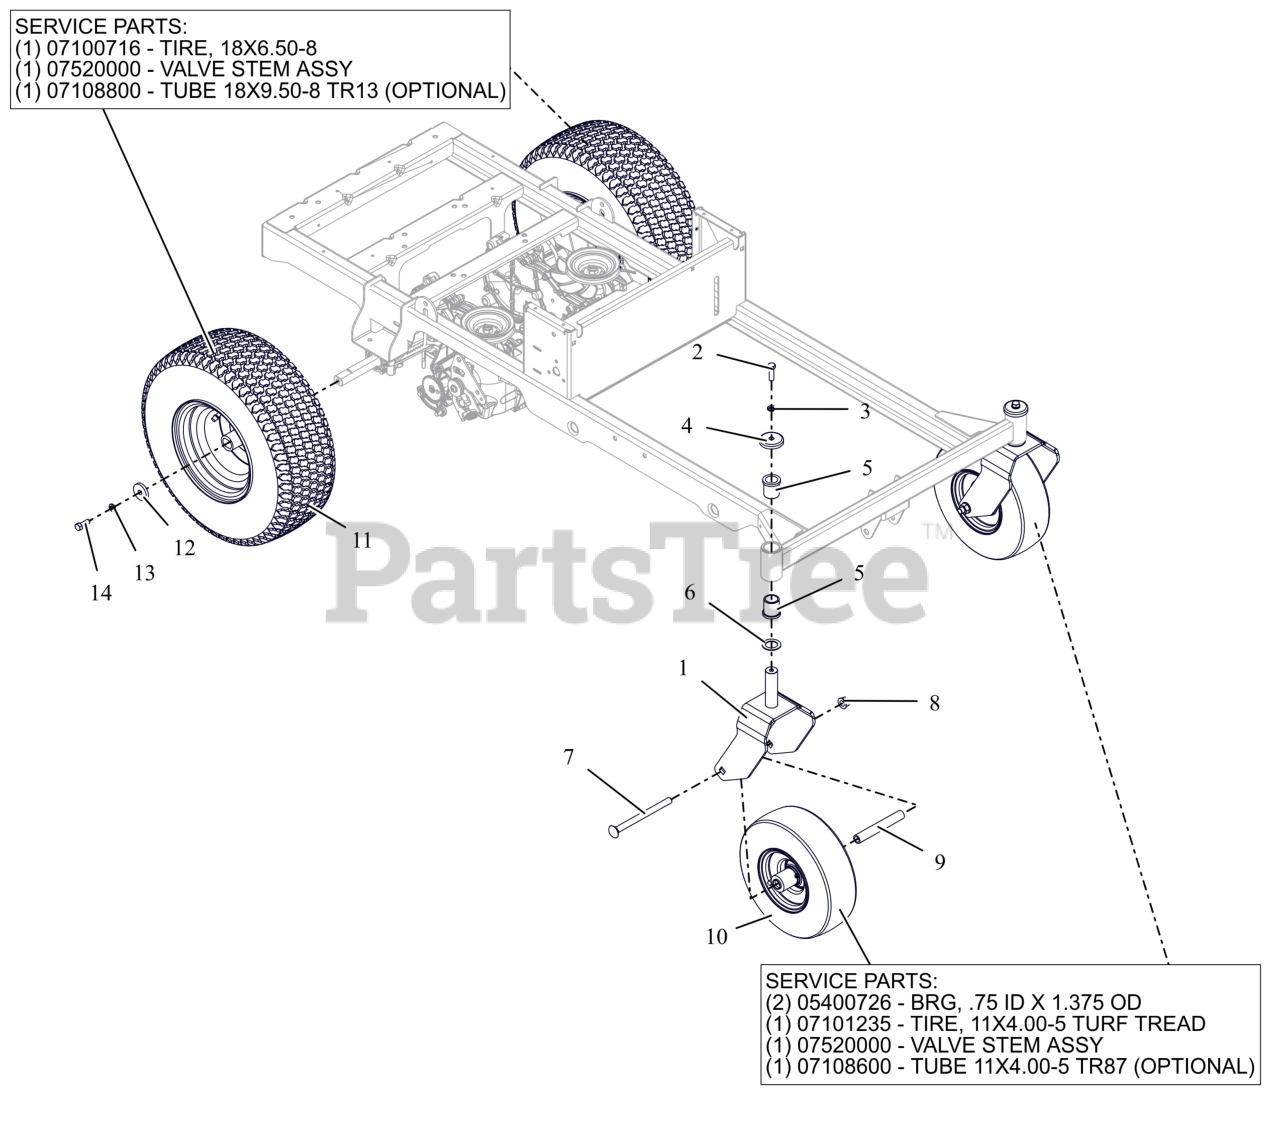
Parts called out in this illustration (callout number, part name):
1	WLDMT- CASTER FORK
2	BLT- HEX .38-16X1.25 G5 ZB500
3	WSHR-LK-REG .375X.094 ZB500
4	SHIELD- AXLE BEARING BLK
5	BSHG-FLG 1.00X1.25X1.50X1.50
6	WSHR-HRD-THRS 1.007X1.542X.062
7	BLT, RHSN .50-13X6.50 G5 ZCC
8	NUT-LK-CTR-FLG .500-13 GG ZCC
9	SPACER, ROLLED WHEEL
10	ASM- WHL/TIRE 11X4.00-5 LG BLK
10	BRG, .75 ID X 1.375 OD
10	LAWN TIRE FRONT, 11/4-5 TURF TREAD
10	VALVE STEM ASS'Y
10	TIRE TUBE, 11/4.0-5 4 PLY TR87 90 BENT VALVE
11	ASM-WHL/TIRE 18 X 6.5-8 LG BLK
11	TIRE, 18X6.5-8
11	VALVE STEM ASS'Y
11	TIRE TUBE 18/6.50/8.50/9.50-8, 20/8.00/10.00-8 4 PLY TR13 STRAIGHT VALVE
12	WSHR, FLT .406X1.50X.245 ZCC
13	WSHR,LK-REG .375X.094 ZCC
14	BLT, HEX .38-16X1.00 G8ZCCEP30
